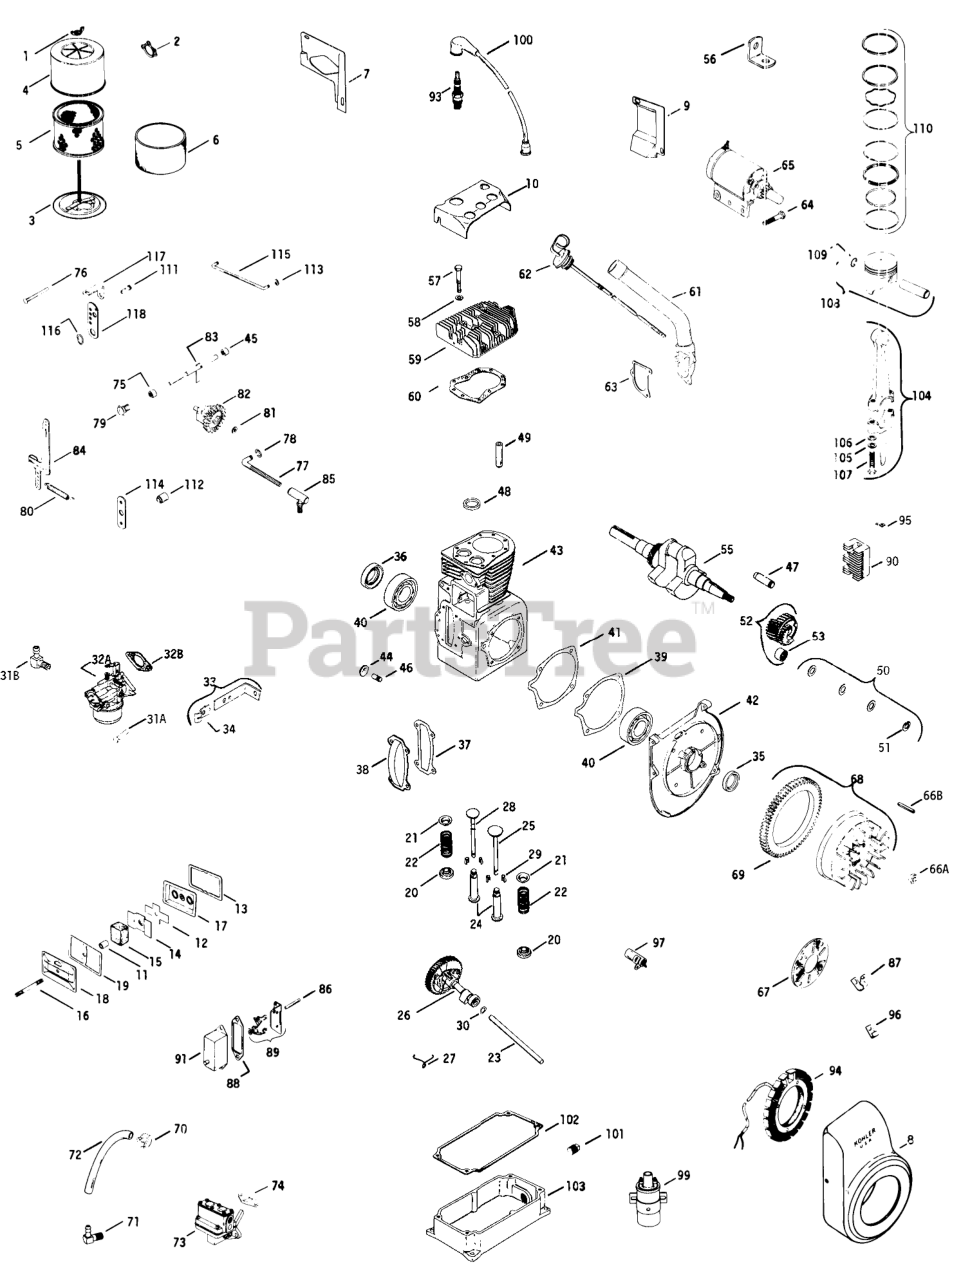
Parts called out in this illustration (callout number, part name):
1	Nut-Wing
2	Gasket-Air Horn
3	Base-Air Cleaner
4	Cover-Air Cleaner
5	Element
6	Element
7	BaffLe side air
8	Housing-Blower
9	Baffle, cylinder
10	Baffle, head
11	Seal
12	Reed
13	Gasket
14	Baffle breather
15	Filter Breather
16	Stud, valve cover
17	Plate
18	Cover valve
19	Gasket
20	Rotator
21	Retainer-Spring
22	Spring
23	Pin (Service)
24	Tappet
25	Valve-Intake
26	Camshaft-assembly
27	Spring-Actuating
28	Valve exhaust
29	Keeper, Valve
30	Spacer
31A	Screw sitd. hd.
31B	Elbow
32A	Carburetor-assembly
32B	Gasket
33	Bracket, choke
34	Clip
35	Seal, Front OiI
36	Seal rear oil
37	Gasket
38	Cover
39	Gasket
40	Ball Bearing
41	Gasket
42	Plate-Bearing
43	Block, cylinder-assembly (Use 45_782_02 Miniblock)
44	Plug
45	Bearing
46	Shaft-Govemor
47	Shaft
48	Insert
49	Guide Valve
50	Kit-Spacer
51	Retainer
52	Gear
53	Bearing,needle
55	Crankshaft
56	Lift Cable
57	Screw
57	Screw-H.C.
58	Washer
59	Head, cylinder
60	Gasket, head
61	Tube, fill
62	Dipstick
63	Gasket
64	Screw
65	Starter-assembly
65	Kit, Brush & Spring
65	Washer
66A	Nut
66B	Key
67	Screen grass
68	Flywheel-assembly
69	Gear Ring
70	Clamp
71	Elbow
72	Line Fuel
73	Pump, fuel
74	Gasket, pump
75	Spacer
76	Pin-GovemorStop
77	Rod ball joint
78	Retainer Rod
79	Bushing
80	Spring-Governor
81	Washer
82	Gear, Governor
83	Shaft, Governor
84	Lever, Governor
85	Ball Joint
86	Rod, breaker
87	Clip
88	Gasket, Cover
89	Breaker
90	Regulator
91	Cover breaker
93	Plug, spark
94	Stator
95	Connector
96	Clip
97	Condenser
99	Coil
100	Kit, Hi-Tension
101	Plug
102	Gasket
103	Base, oil pan
104	Rod, conn.-assembly Std.
104	Rod conn.-assem. (.010 U.S.)
105	Washer
106	Washer
107	Screw, connecting rod
108	Piston-assembly (Std.)(Includes pin & retainers)
108	Piston-assembly (.003)(Includes pin & retainers)
108	Piston-assembly (.010)(Includes pin & retainers)
108	Piston-assembly (.020)(Includes pin & retainers)
108	Piston-assembly (.030)(Includes pin & retainers)
109	Pin, Retainer
110	Ring set-Std. & .003
110	Ring set-.010
110	Ring set-.020
110	Ring set-.030
111	Clamp, swivel wire
112	Spacer
113	Retainer Rod
114	Bellcrank
115	Rod, throttle
116	Washer
117	Spacer
118	Bracket
118	Gasket Set
118	Miniblock
118	Shortblock
118	Service Engine
